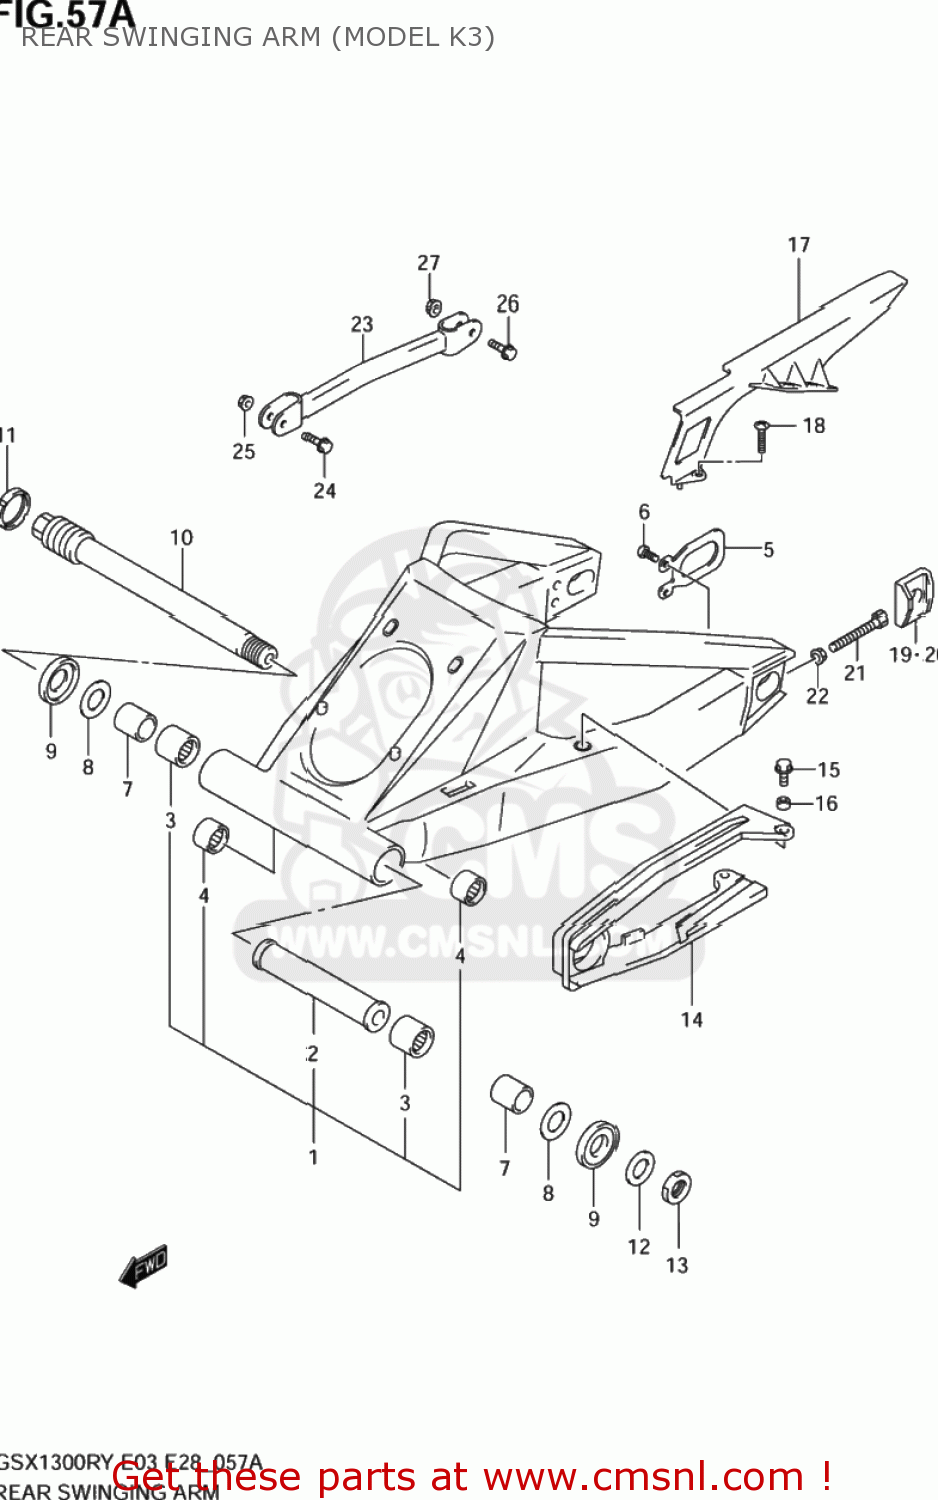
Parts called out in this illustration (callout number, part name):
1	SWINGINGARM ASSY,RR
2	SPACER,REAR SWING PIVOT,CENTER
3	BEARING(30X40X25)
4	BEARING(20X27X23.5)
5	PLATE,RR SWING ARM BRKT
6	SCREW
7	SPACER,REAR SWING ARM PIVOT
8	WASHER
9	DUST SEAL,RR SWGARM PIVOT
10	SHAFT,RR SWINGINGARM PIVOT
11	NUT,RR SWGARM PIVOT BOLT
12	WASHER(25.2X42X3.2)
13	NUT
14	BUFFER,CHAIN TOUCH DEFENSE
15	BOLT(6X20)
16	SPACER(6.5X9X5)
17	CASE,CHAIN
18	SCREW(6X16)
19	ADJUSTER,CHAIN,L
20	ADJUSTER,CHAIN,R
21	BOLT(8X50)
22	NUT
23	TORQUELINK,RR
24	BOLT(8X35.5)
25	NUT
26	BOLT(10X37)
27	NUT
